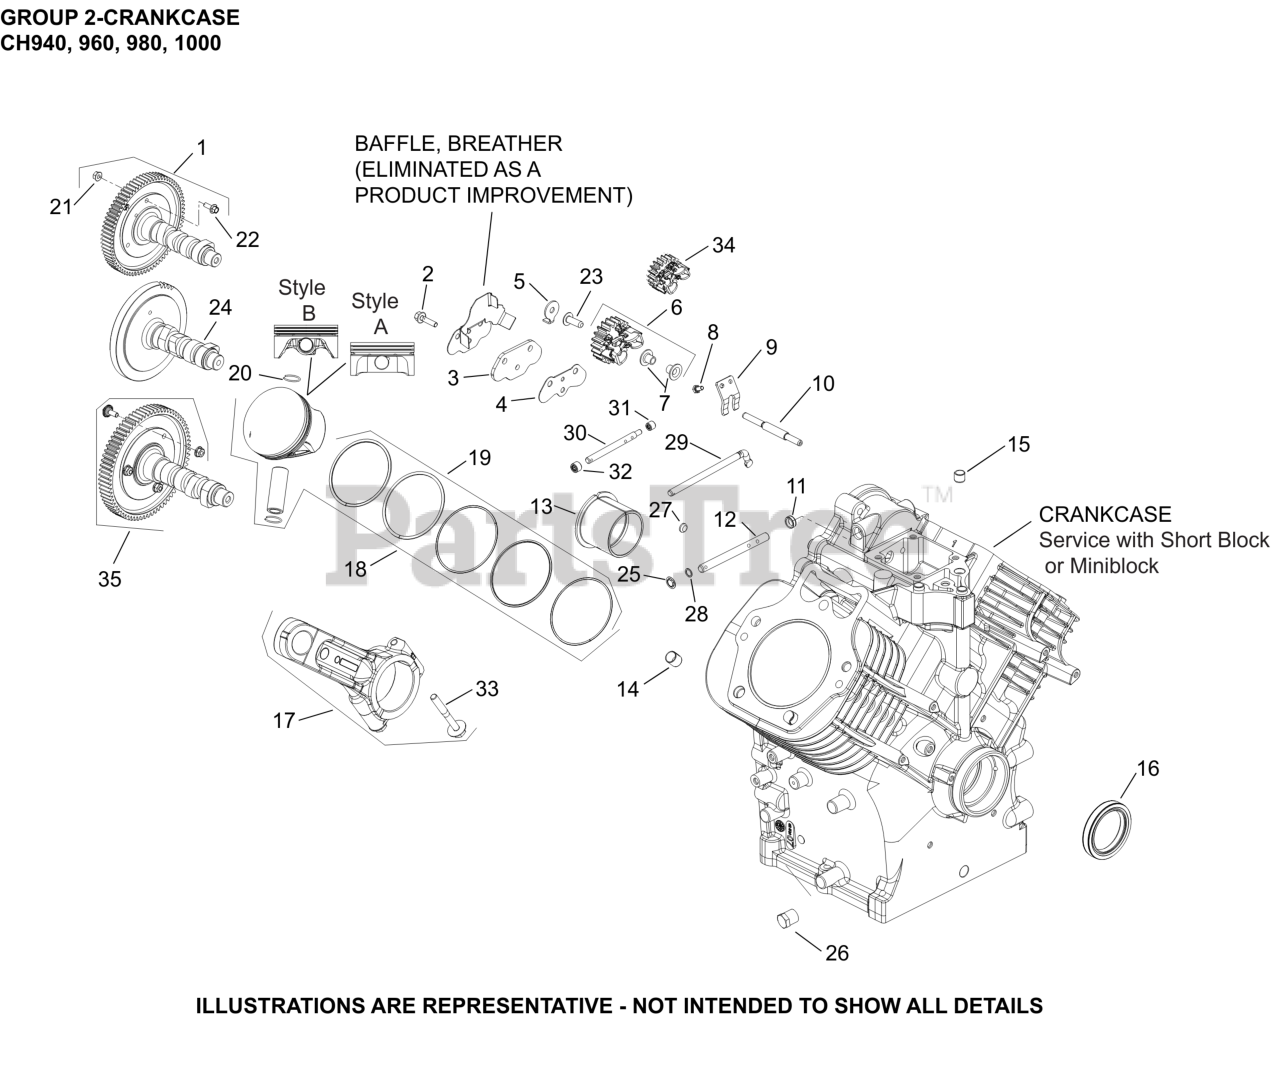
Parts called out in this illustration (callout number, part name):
3	KIT, COVER, LIFTER FEED
4	GASKET, LIFTER FEED COVER
5	TAB, LOCKING
7	PIN, GOVERNOR REGULATING
8	SCREW, HEX HEAD
9	YOKE, GOVERNOR
10	SHAFT, GOVERNOR GEAR
11	SEAL, GOVERNOR CROSS SHAFT
12	SHAFT, GOVERNOR CROSS
14	PIN, LOCATING
16	SEAL, OIL FW SIDE, BLACK
17	CONNECTING ROD ASSEMBLY
18	KIT, PISTON (STD)
18	KIT, PISTON (0.25 OS)
18	KIT, PISTON (0.50 OS)
19	RING, SET PISTON (STD)
20	RETAINER, PISTON PIN
34	KIT, GOVERNOR GEAR
NI	KIT, ROD BOLTS
NI	SCREW, HEAVY HEX FLANGE
NI	KIT, CAMSHAFT
